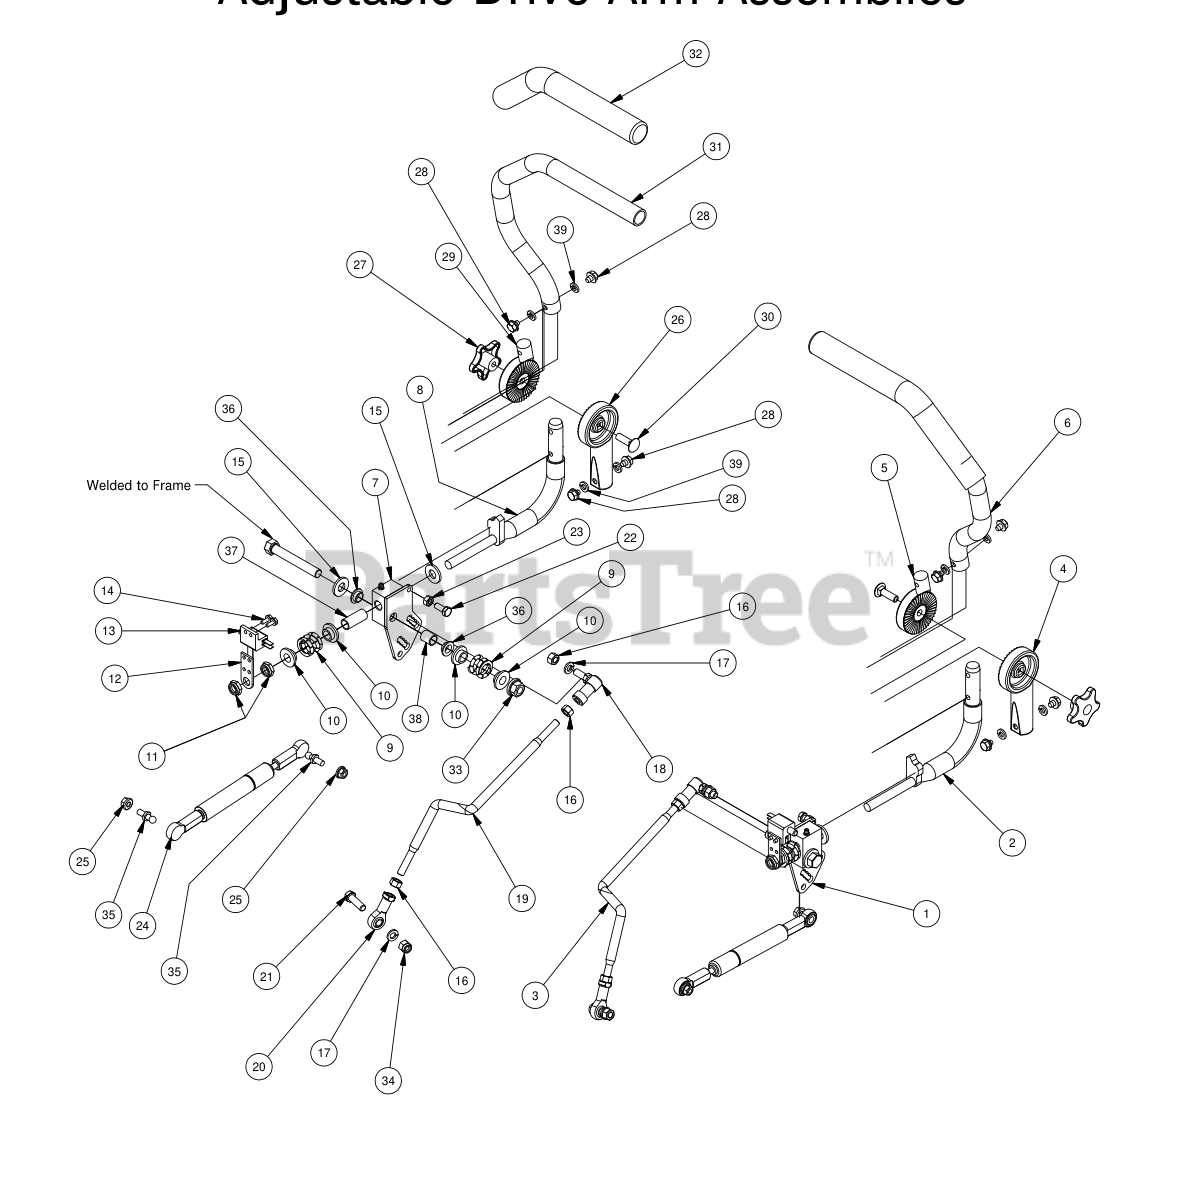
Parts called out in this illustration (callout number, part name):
1	2013 Drive Lever Housing (Right)
2	Steering Arm Elbow - Right
3	Push Rod Right
4	Lower Adjuster - Steering Arm- Right
5	Upper Adjust Steering Arm- Right
6	Upper Tube-Adjustable Steering
7	2013 Drive Lever Housing (Left)
8	Steering Arm Elbow - Left
9	Drive Lever Spring
10	.515 ID Nylon Shoulder Washer
11	1/2" Nylock Nut (1/2 Jam)
12	MZ Switch Bracket
13	Safety Switch
14	12-24x 1/2 HWH Bolt
15	.505 Nylon Spacer
16	3/8" Fine Threaded Jam Nut
17	3/8" Lock Washer
18	3/8-24 Quick Release Ball Joint
19	Push Rod Left
20	Spherical Rod End - Outlaw
21	3/8" x 1 1/4" Hex Bolt
22	5/16" x 3/4" Hex Bolt
24	Steering Damper
25	5/16" Flange Nut
26	Lower Adjuster - Steering Arm- Left
27	Black Knob for Adjustable Steering Arm
28	5/16-18 1/2 HWH Bolt-Steering
29	Upper Adjuster-Steering Arm- Left
30	3/8" x 1 1/4" Carriage Bolt
31	Upper Tube-Adjustable Steering
32	Black Steering Grip
33	1/2-13 Mechanical Lock Nut Grade F
34	3/8 Nylock Nut
35	10mm Damper Ball Stud-Steering
36	1/2" Oil Impregnated Bushing
37	Drive Arm Block Insert-long
38	Drive Arm Block Insert-short
39	5/16" Lock Washer
